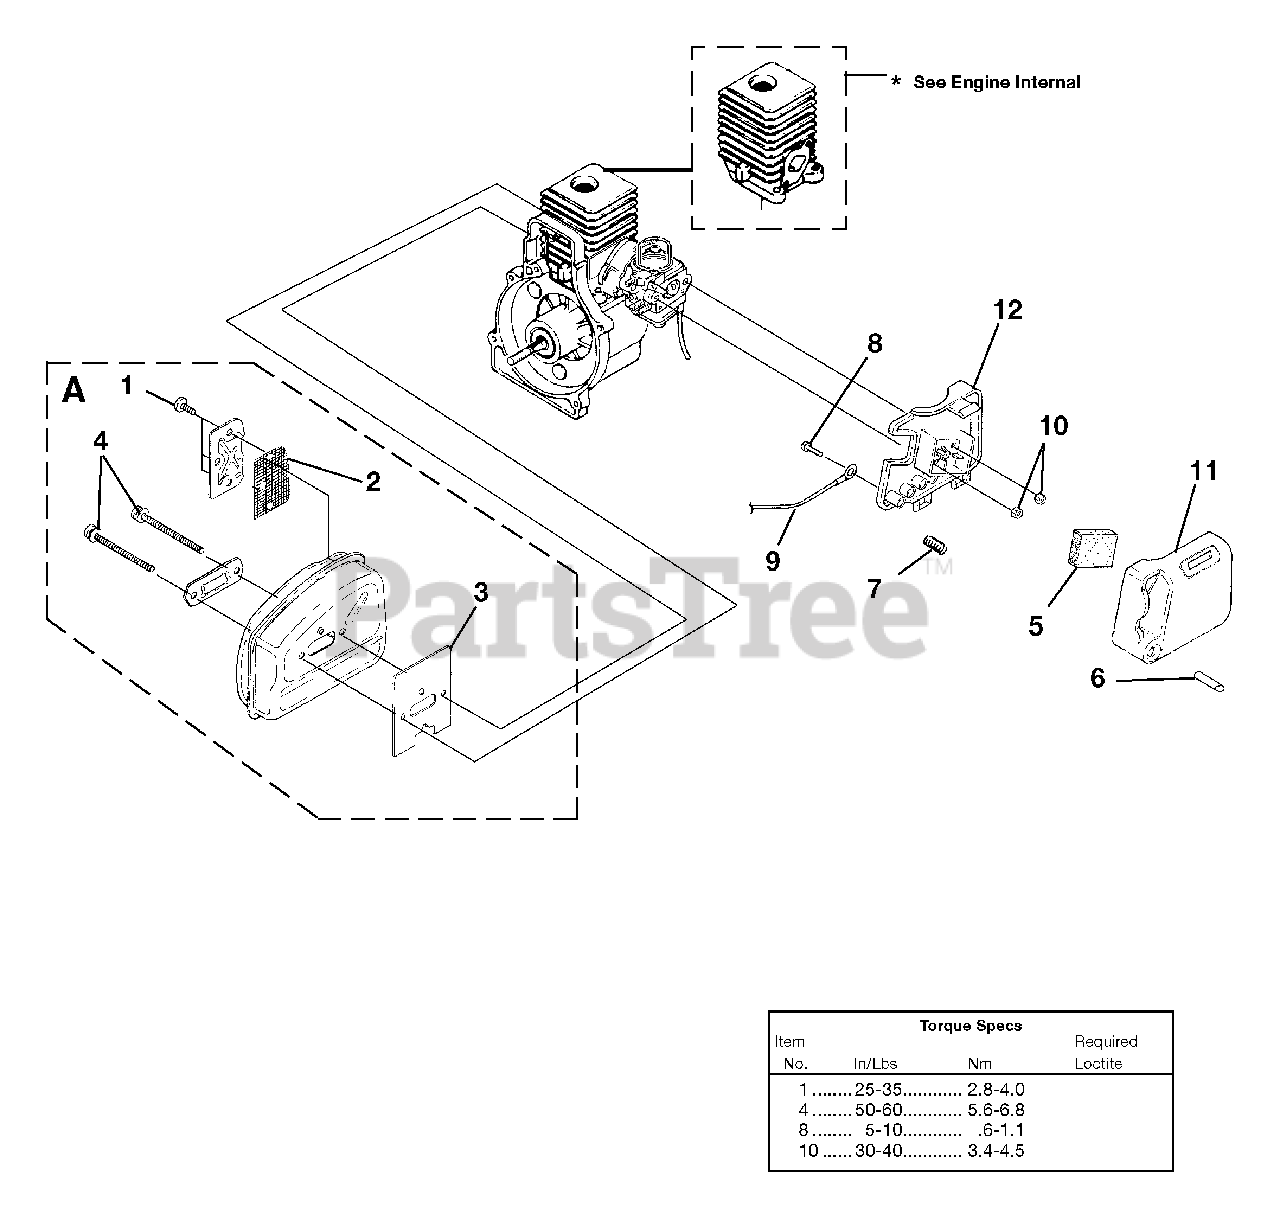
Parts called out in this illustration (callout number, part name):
1	SCREW, Taptite- (8-32 X 3/8")
2	SCREEN-Spark
3	GASKET-Muffler
4	SCREW, Truss Hd. - (10-24 X 2.188)
5	FILTER-Air
6	BUTTON-Switch
7	SPRING-Compression
8	SCREW-Thread Form (6-19 x 1/2")
9	LEAD-Electrical
10	NUT-Hex (10-24)
11	COVER, Air Box
12	BOX, Air Filter
A	MUFFLER ASSY.
